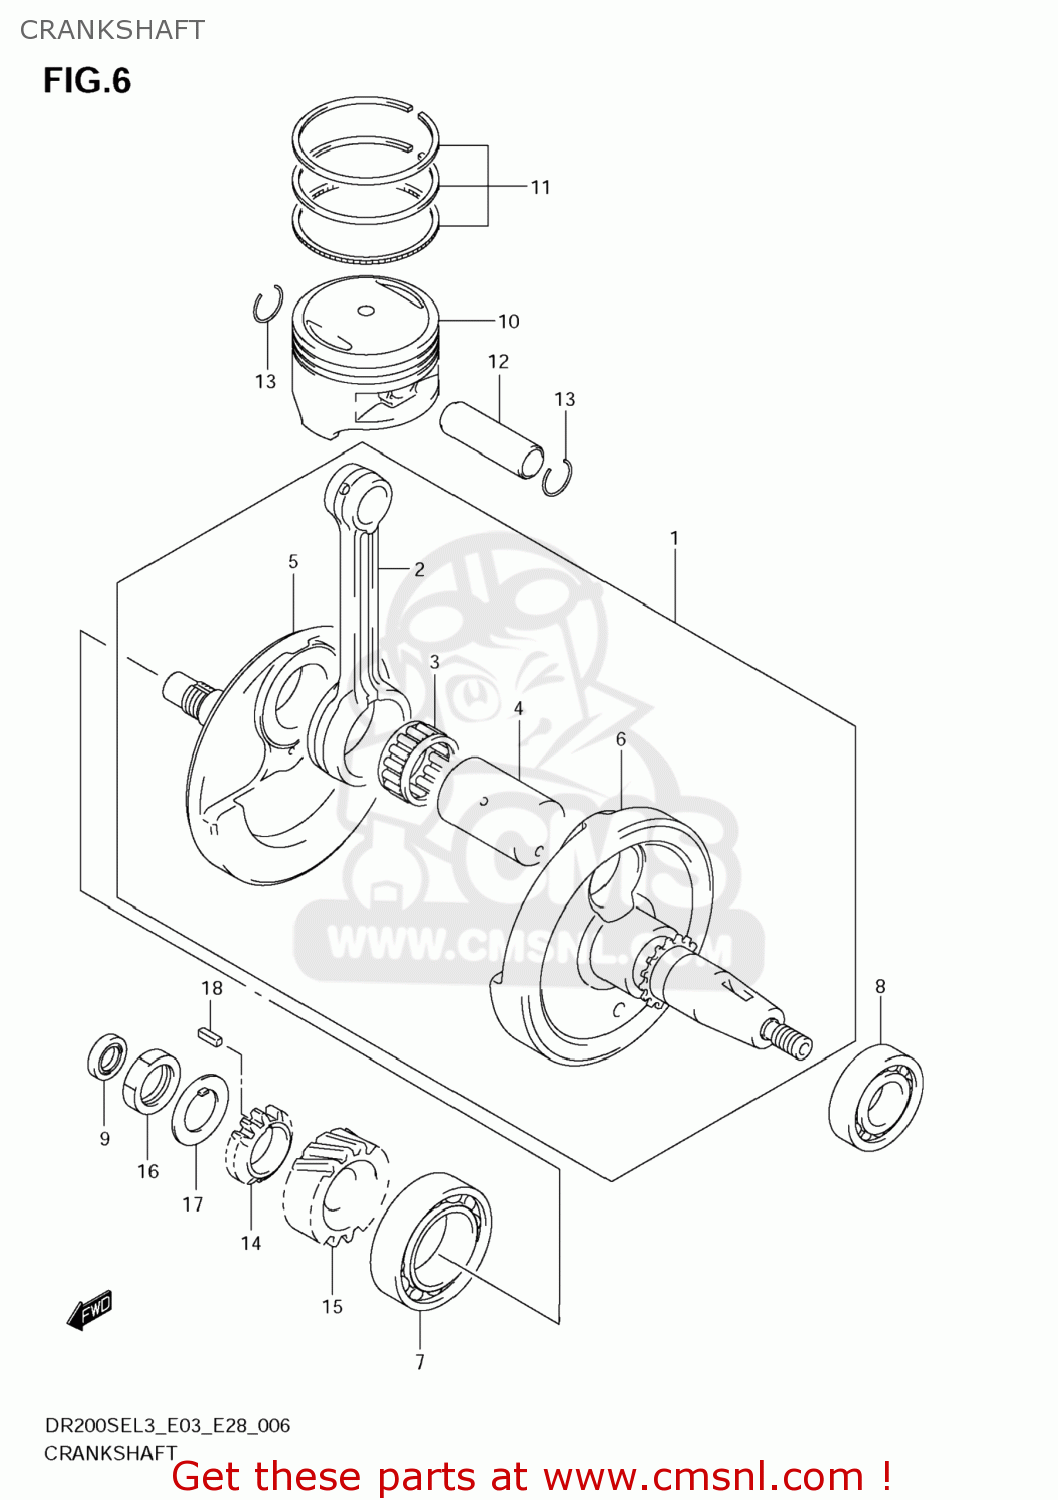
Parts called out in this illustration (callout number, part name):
1	CRANKSHAFT ASSY
2	CONNECTING ROD
3	BEARING(31X38X18)
4	PIN,CRANK
5	CRANKSHAFT,R
6	CRANKSHAFT,L
7	BEARING(28X68X18)
8	BEARING(35X72X17)
9	SEAL,OIL(12X21X7)
10	PISTON
11	RING SET,PISTON
12	PIN,PISTON
13	RING,SNAP 16MM
14	GEAR,OIL PUMP DRIVE(NT:15)
15	GEAR,PRIMARY DRIVE
16	NUT
17	WASHER
18	KEY
